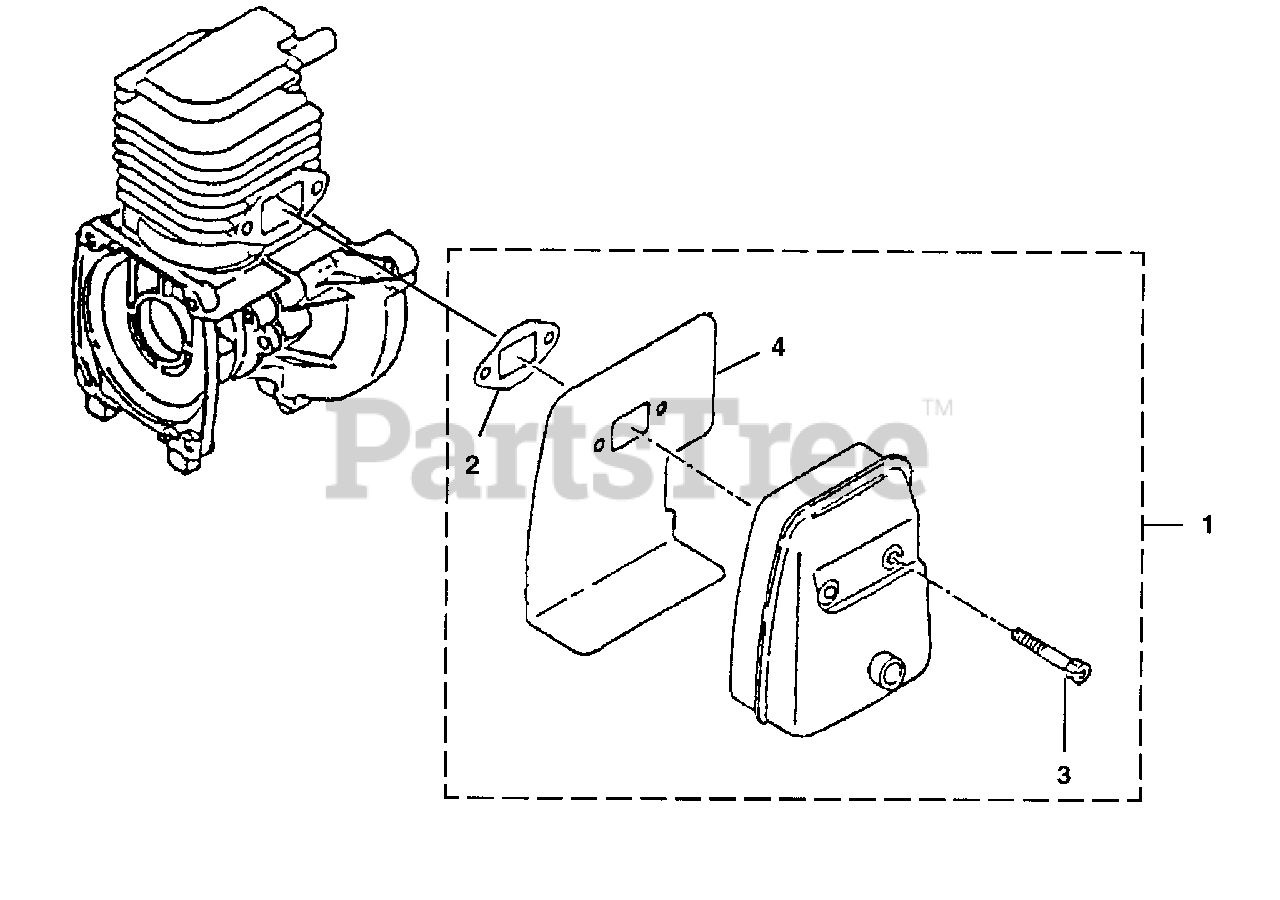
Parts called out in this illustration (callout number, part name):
1	MUFFLER ASSEMBLY
2	GASKET-Muffler
3	SCREW-Socket Hd (M5 x 45)
4	INSULATOR-Muffler
